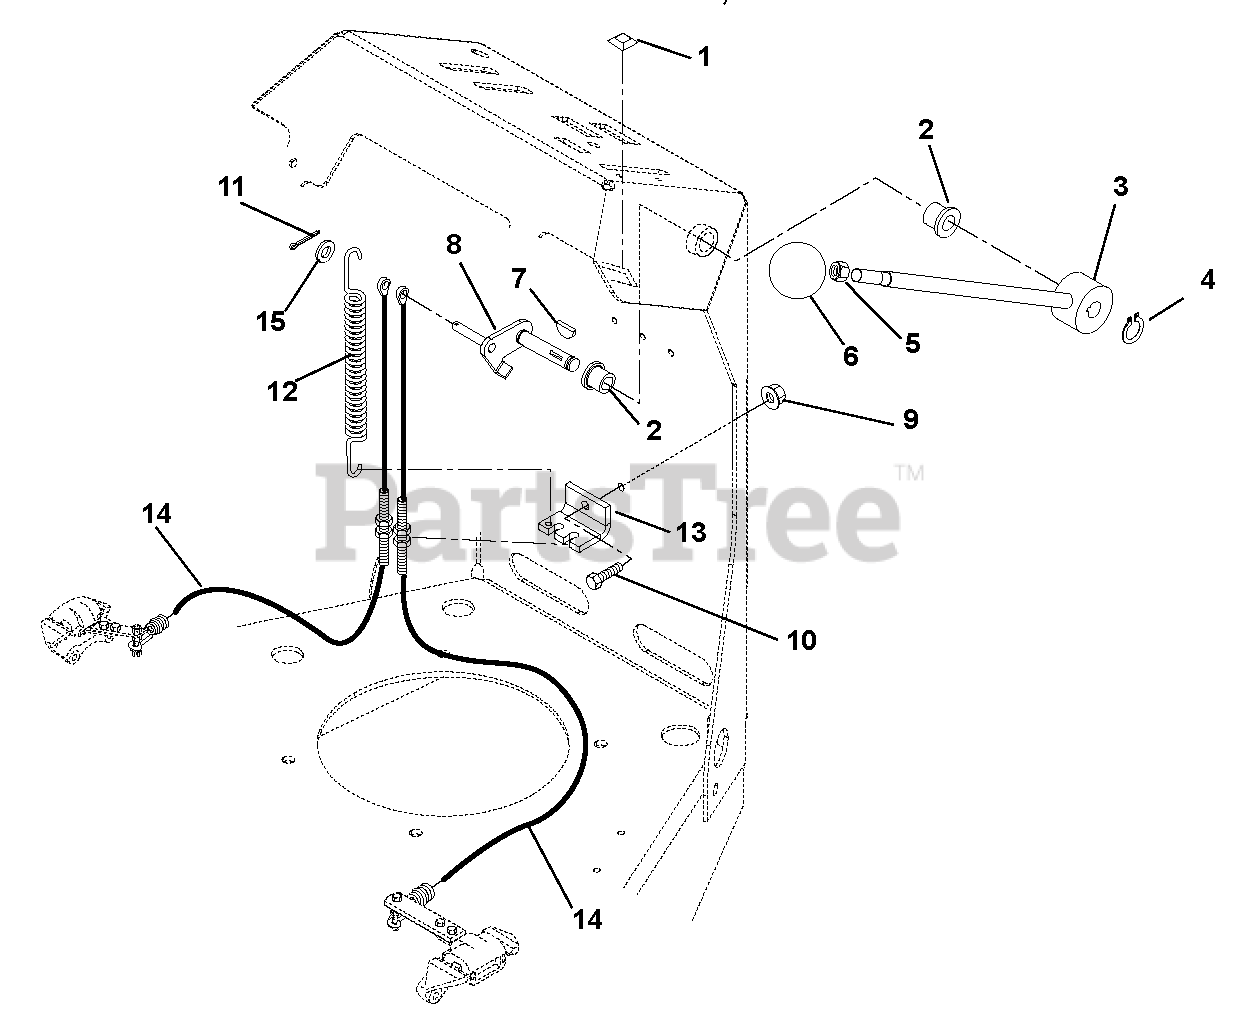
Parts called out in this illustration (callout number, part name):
2	Bushing, Flange .50 x .75 x .75 x .125
3	Weldment, Parking Brake Lever
4	Ring, Retaining External .50 x .05
5	Nut, Hex Jam .38-16
6	Knob, Steering Lock
7	Key, Woodruff .13 x .63
8	Weldment, Shaft Brake Activation
9	Nut, Locking Top Flange .31-18
10	Bolt, Hex .31-18 x 1.00 Grade 5
11	Pin, Cotter .09 x .75
12	Spring, Extension
13	Bracket, Cable
14	Cable, Parking Brake
15	Washer, Flat Steel .344 x .688 x .065
